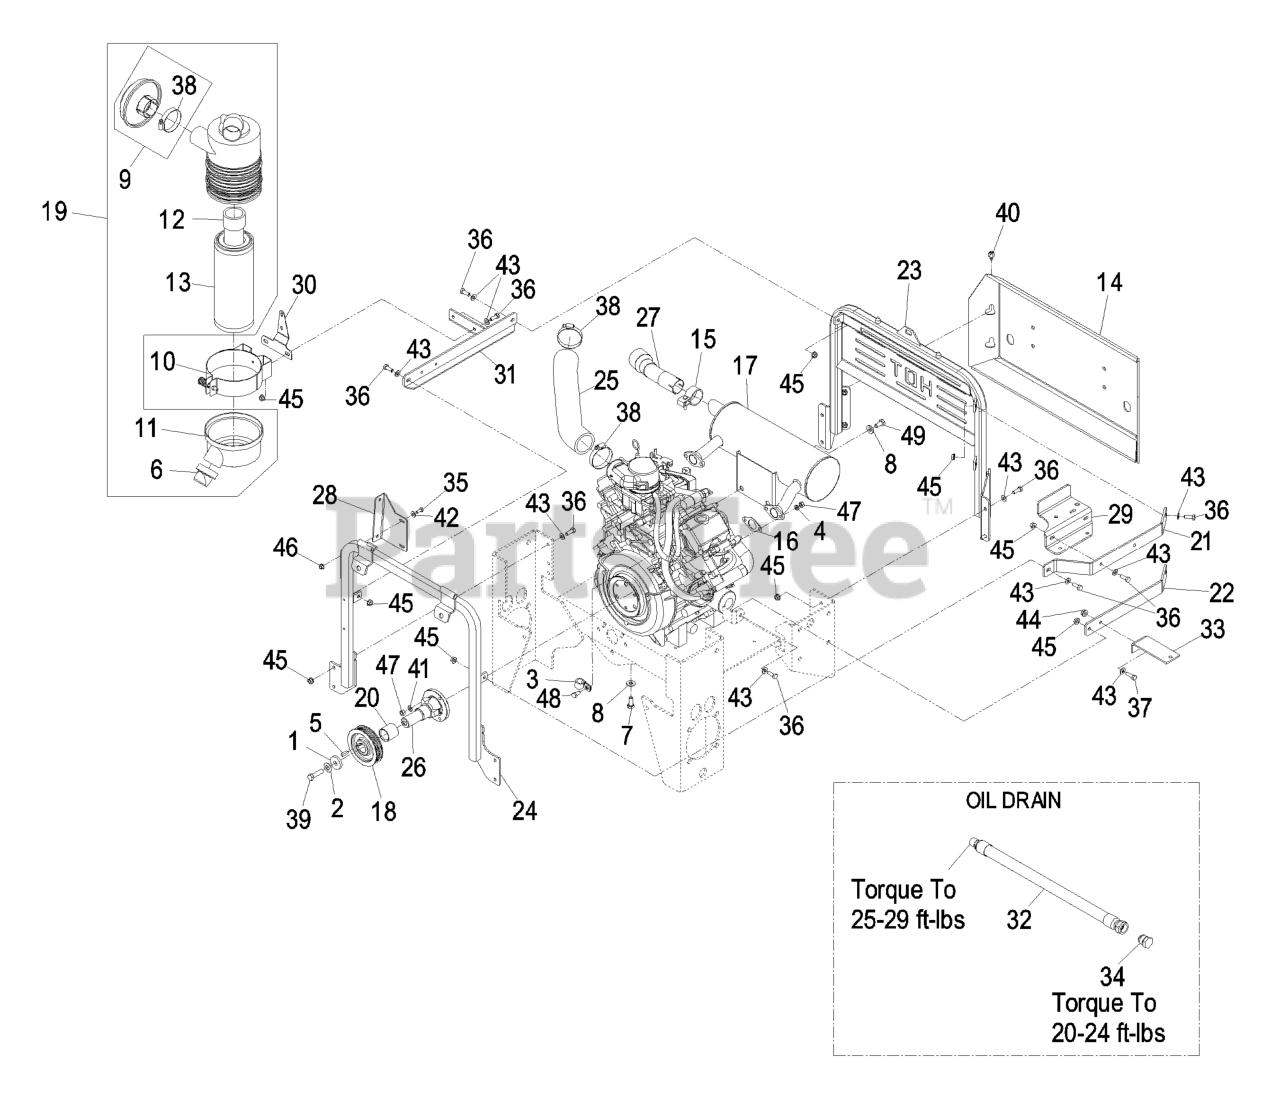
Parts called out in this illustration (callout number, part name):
1	WASHER-CLUTCH
2	WASHER-SPRING
3	CLIP-LOOM
4	WASHER-LOCK
5	KEY-SQUARE
6	VALVE-VACUATOR
7	SCREW-HH
8	WASHER-BELLEVILLE
9	HOOD-CLEANER, 2" AIR INTA
10	BRACKET-FILTER, AIR
11	COVER-FILTER, AIR
12	FILTER-AIR, SAFETY
13	FILTER-AIR
14	WLD,REAR BUMPER
15	CLAMP-MUFFLER
16	GASKET-EXHAUST
17	KIT,MUFFLER
18	SHEAVE,5K 4"PD POLY-V
19	FILTER-AIR
20	SPACER,ENGINE SHEAVE
22	RIB, BOTTOM
24	ASM, RAD. MOUNT W/ DECALS
26	SHAFT, STUB
28	BRACKET,FRONT COVER
29	BRACKET,BOTTLE
30	BRACKET,REAR COVER
31	ASM,AIR CLNR BRKT W/ DECA
33	BRACKET, HYDRAULIC TANK
35	SCREW-HH
36	SCREW-HH
37	SCREW-HH
38	CLAMP-HOSE
39	SCREW-HH
40	SCREW-HHF
41	WASHER-LOCK
42	WASHER-FLAT
43	WASHER-PLAIN
44	NUT-HHF, WHIZ
47	NUT-HEX
48	SCREW-HH
49	SCREW-HH
